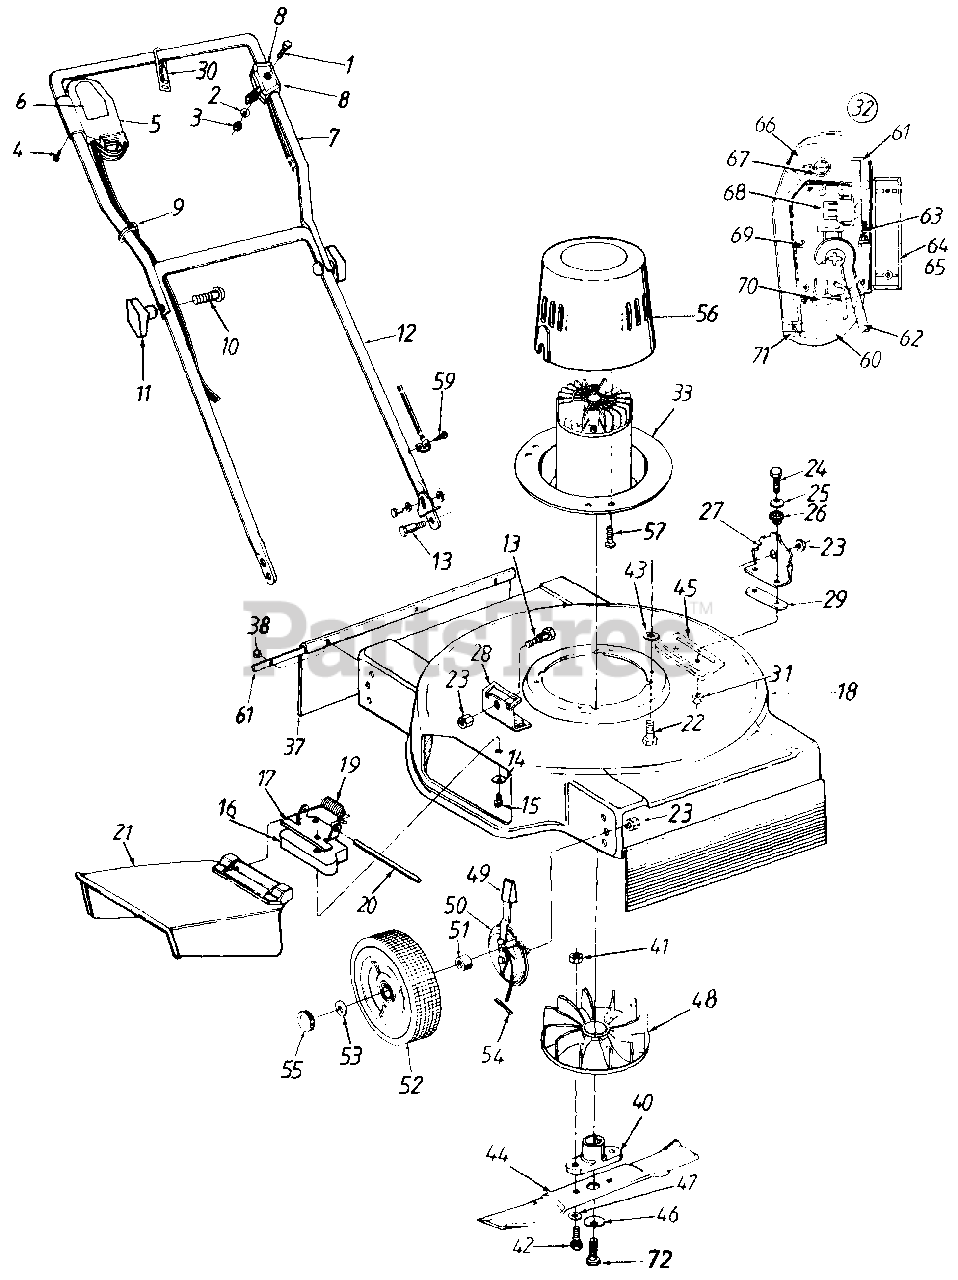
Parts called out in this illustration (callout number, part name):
1	Hex Bolt 1/4-20 x 1.5" Lg.
2	Fl-Wash. .281" I.D. x .5" O.D.
3	Acorn Nut 1/4-20 Thd.
4	Self-Tap Scr. #7 x 1" Lg.
6	Label - Switch Box
7	Upper Handle
8	Control Flip Knob
9	Cable Tie
10	Curved Carr. Bolt 5/16-18 x 2" Lg.
11	Hand Knob
12	Lower Handle
13	Shld. Bolt 3/8-16 Thd.
14	Bell-Wash. 1/4" I.D.
15	Self-Tap Scr. 1/4-20 x 1.12" Lg.
16	Spacer
17	Adapter Plate
20	Hinge Pin
21	Chute Deflector Ass'y.
22	Hex Self-Tap Scr. 3/8-16 x .75" Lg.
23	Hex Sems Nut 3/8-16 Thd.
24	Hex Bolt 1/4-20 x 1" Lg.
25	Fl-Wash. .26" I.D. x .72" O.D.
26	Insulator Shield
27	Handle Brkt.- L.H.
28	Handle Brkt.- R.H.
29	Insulator Strap
30	Cord Restraint
31	Hex Nylon Lock Nut 1/4-20 Thd.
32	Cord & Switch Ass'y. Comp.
33	Motor & Switch Ass'y. Comp.
37	Flap - Rear & Front
38	Pop Rivet .188" Dia.
40	Blade Adapter
41	Hex Nut 3/8-24 Thd.
42	Hex Bolt 3/8-24 x 1.25" Lg.
43	Spacer
44	19" Blade
45	Deck Reinforcement Plate
46	Bell-Wash. .4" I.D. x 1.14" O.D.
47	Bell-Wash. 3/8" I.D.
48	Motor Fan
50	Height Adj. Ass'y. (RF/LR)
51	Plastic Wheel Spacer
52	7" Wheel
53	Fl-Wash. .531" I.D. x .875" O.D.
54	Cotter Pin 3/32" Dia. x .75" Lg.
55	Hub Cap
56	Motor Cover
57	Screw #10 x .75" Lg.
59	Self-Tap AB-Tap Scr. #10-16 x .5" Lg.
60	Retainer Plug
61	Latch
62	Cord Ass'y.
63	Spring Latch
64	Housing - Upper Half
66	Handle - Switch Actuator
67	Spring - Switch Handle
68	Switch
69	Screw #6-32 x .5" Lg.
70	Plug Ass'y.
71	Retainer Plug Spring
72	Hex Bolt 3/8-24 x 2.5"
